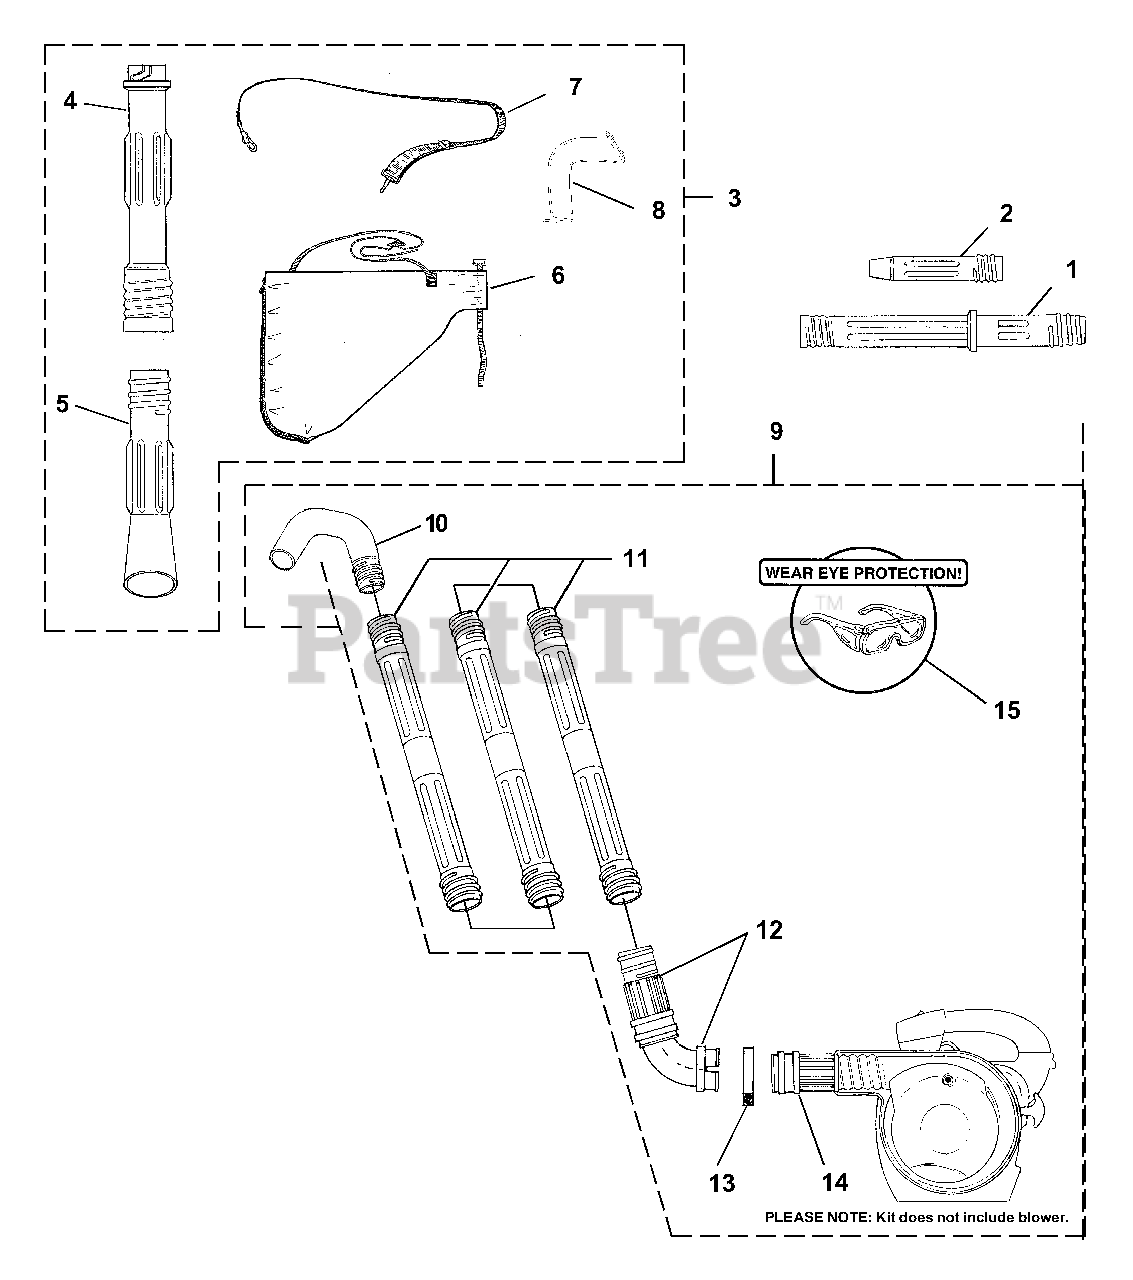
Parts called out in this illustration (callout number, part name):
1	Tube, Blower
2	Nozzle, Blower
3	Vacuum Kit
4	Vac Tube, Upper
5	Vac Tube, Lower
6	Bag
7	Shoulder Strap
8	Air Deflector
9	Gutter Maintenance Kit
10	Full Elbow
11	Straight Tube
12	Upper Elbow & Swivel Adapter
13	Large Clamp
14	Adapter
15	Safety Glasses - Clear
